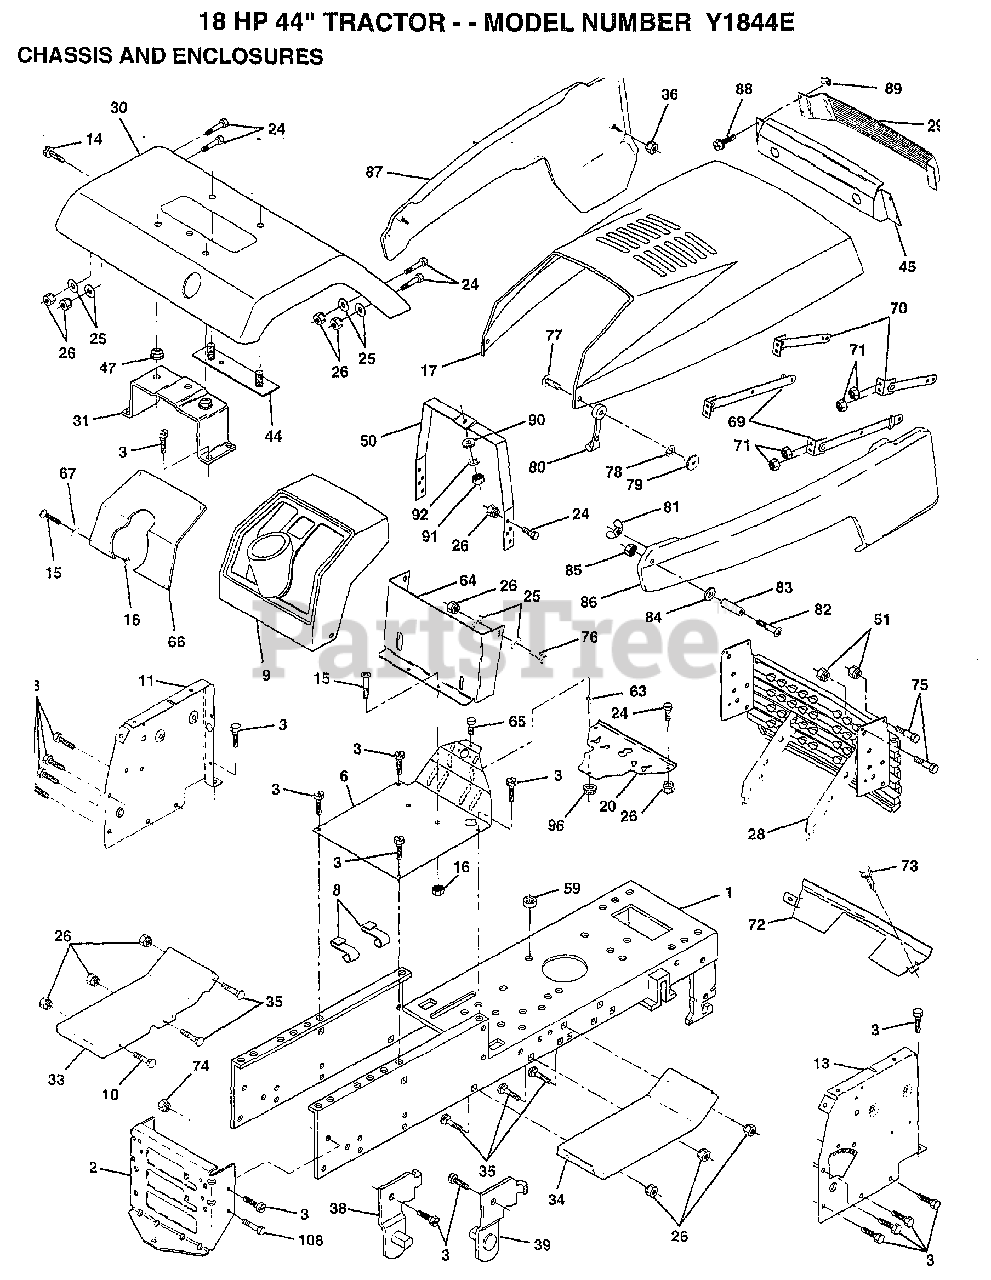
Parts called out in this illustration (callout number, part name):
2	DRAW BAR
3	SCREW
8	"CLIP,INSULATOR"
9	DASHBOARD BLACK
11	PANEL.DASH.LH
13	PANEL.DASH.RH
14	SCREW LT
15	SCREW
20	PLATE.SUPT.BATTER
24	BOLT
25	WASHER
26	NUT
29	LENS LT
30	FENDER.PNT.
31	BRKT.ASM.FENDER
35	BOLT
36	PAL NUT LT
38	BRACKET ASM LH
39	BRACKET ASM RH
44	STRAP ASM FENDER
47	NUT-PUSH YT
50	SUPPORT ASS'Y
51	NUT
63	SPACER
64	LOWER DASH
65	BOLT
66	PLATE SLKSCR YP
67	WASHER
71	NUT HXKEP 1/4X20
72	STRAP.GRILLE.PNT.
73	SCREW CRT
76	BOLT
77	SCREW
78	LOCKWASHER
79	WELDNUT
80	HOOD LATCH T
82	SCREW
83	SPACER LT
84	WASHER
86	PANEL SIDE RH
89	"""J"" FASTENER LT"
90	WASHER PM
92	LOCKWASHER
96	NUT
